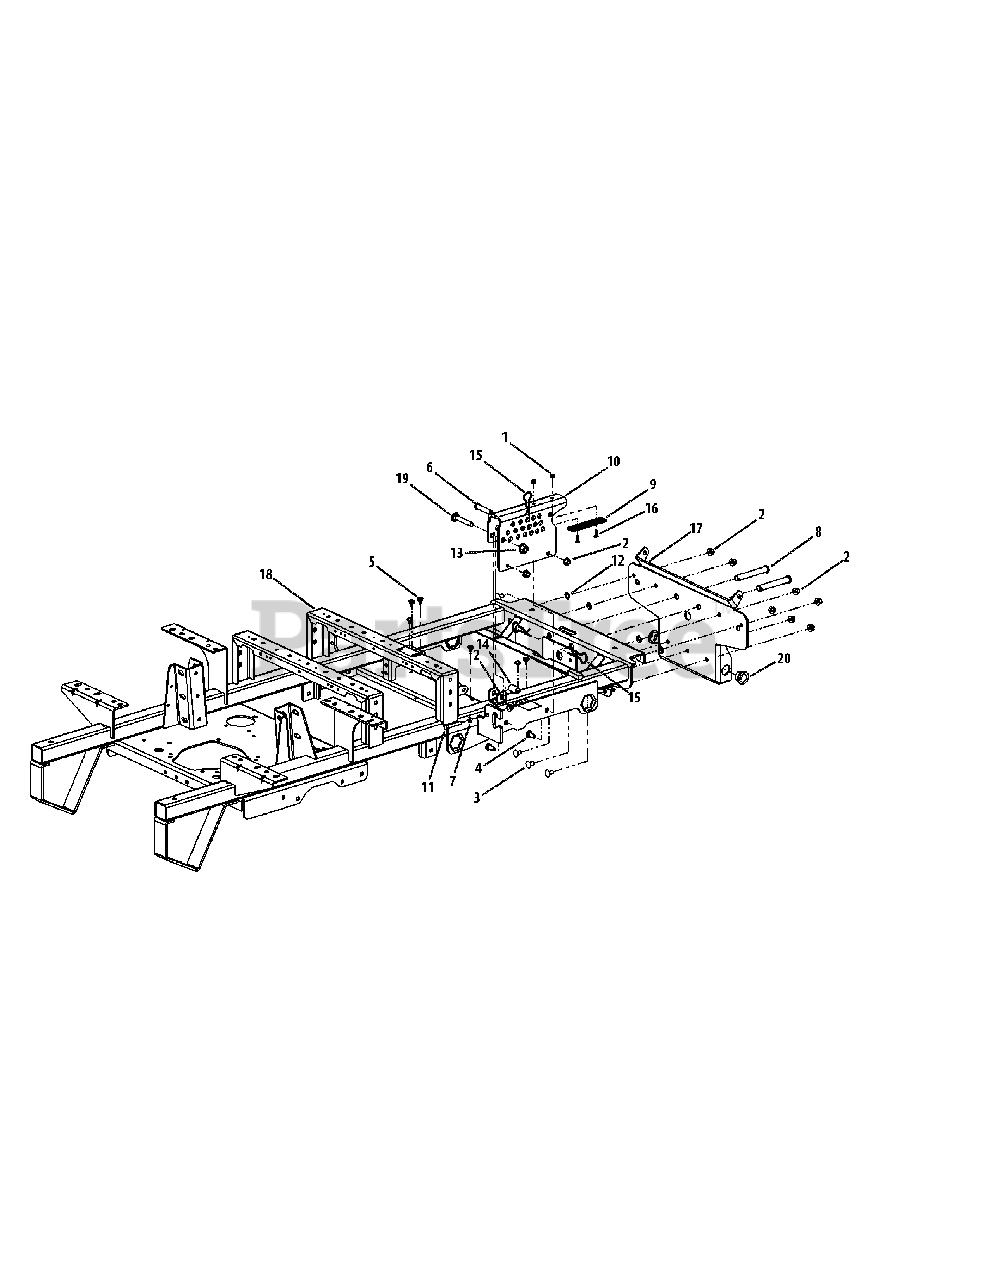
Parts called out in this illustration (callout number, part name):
1	Lock Nut w/Nylon Insert
2	Hex Nut, 3/8-16 Flange Lock
3	Carriage Bolt, 3/8-16 x .75 Long
4	Carriage Bolt, 3/8-16 x 1
5	Rubber Bumper, .62 OD x .22 Thick
6	Clevis Pin, .500 Dia. x 2.50 Lg.
7	Nut, 3/8-16, Jam
8	Clevis Pin, .625 Dia x 4.375 Long
9	Wear Plate, 1.25 x 5.00
10	Lift Index Bracket
11	Hex Cap Screw 3/8-16 x 2.00
12	Push Retainer, 3/8
13	Nut, 1/2-13, Flangelock
14	Spacer, .51 ID x .75 OD x 1.40
15	HitchPin, .120 Dia. x 3.0
16	Flat Head Cap Screw, 1/4-20 x .75
17	Bracket Assembly, Frame, Front
18	Frame Assembly
19	Carriage Bolt, 1/2-13 x 3.00
20	Bushing, 1.00 ID x 1.50 OD x .75
